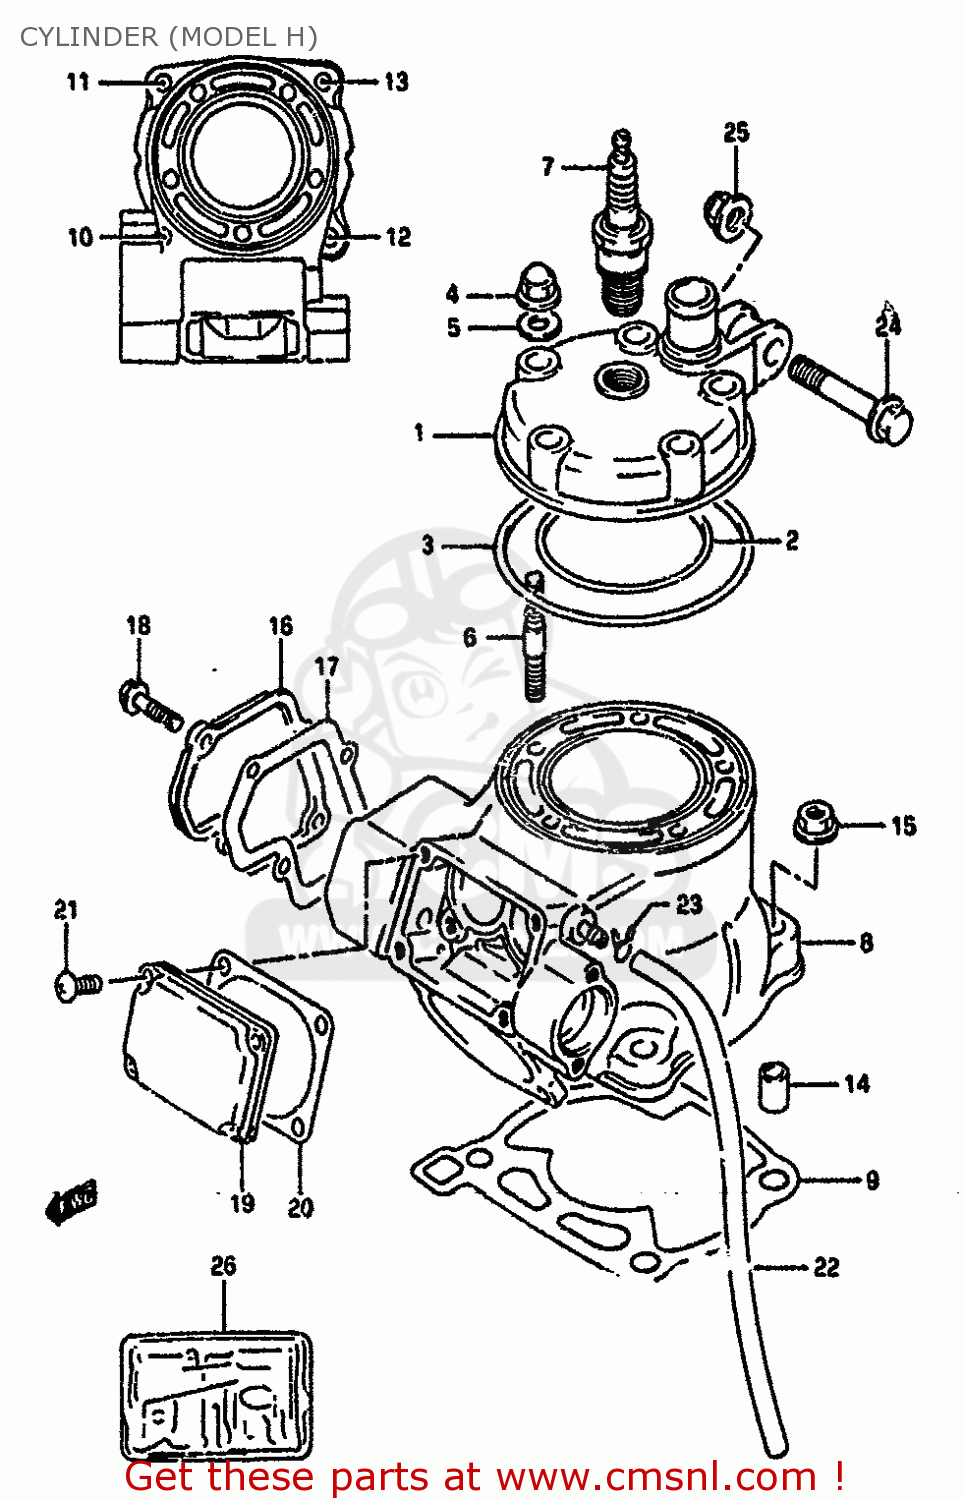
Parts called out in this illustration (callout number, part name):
1	HEAD,CYLINDER
2	O RING,CYLINDER HEAD NO.1
3	O RING,CYLINDER HEAD NO.2
4	NUT
5	GASKET(8.5X17X2.3) (NAS)
6	BOLT,STUD
7	SPARK PLUG BR9EV
8	CYLINDER
9	GASKET,CYLINDER (NAS)
10	STUD 8X25
11	BOLT,STUD
12	STUD BOLT
13	BOLT,STUD
14	PIN
15	NUT
16	COVER,CYLINDER NO.1
17	GASKET,CYLINDER COVER (MCA)
18	BOLT
19	COVER,CYLINDER NO.2
20	GASKET,CYLINDER COVER NO.2 (NAS)
21	SCREW
22	HOSE
23	CLAMP
24	BOLT(8X41)
25	NUT
26	GASKET SET (MCA)
27	NUT
28	GASKET SET (MCA)
